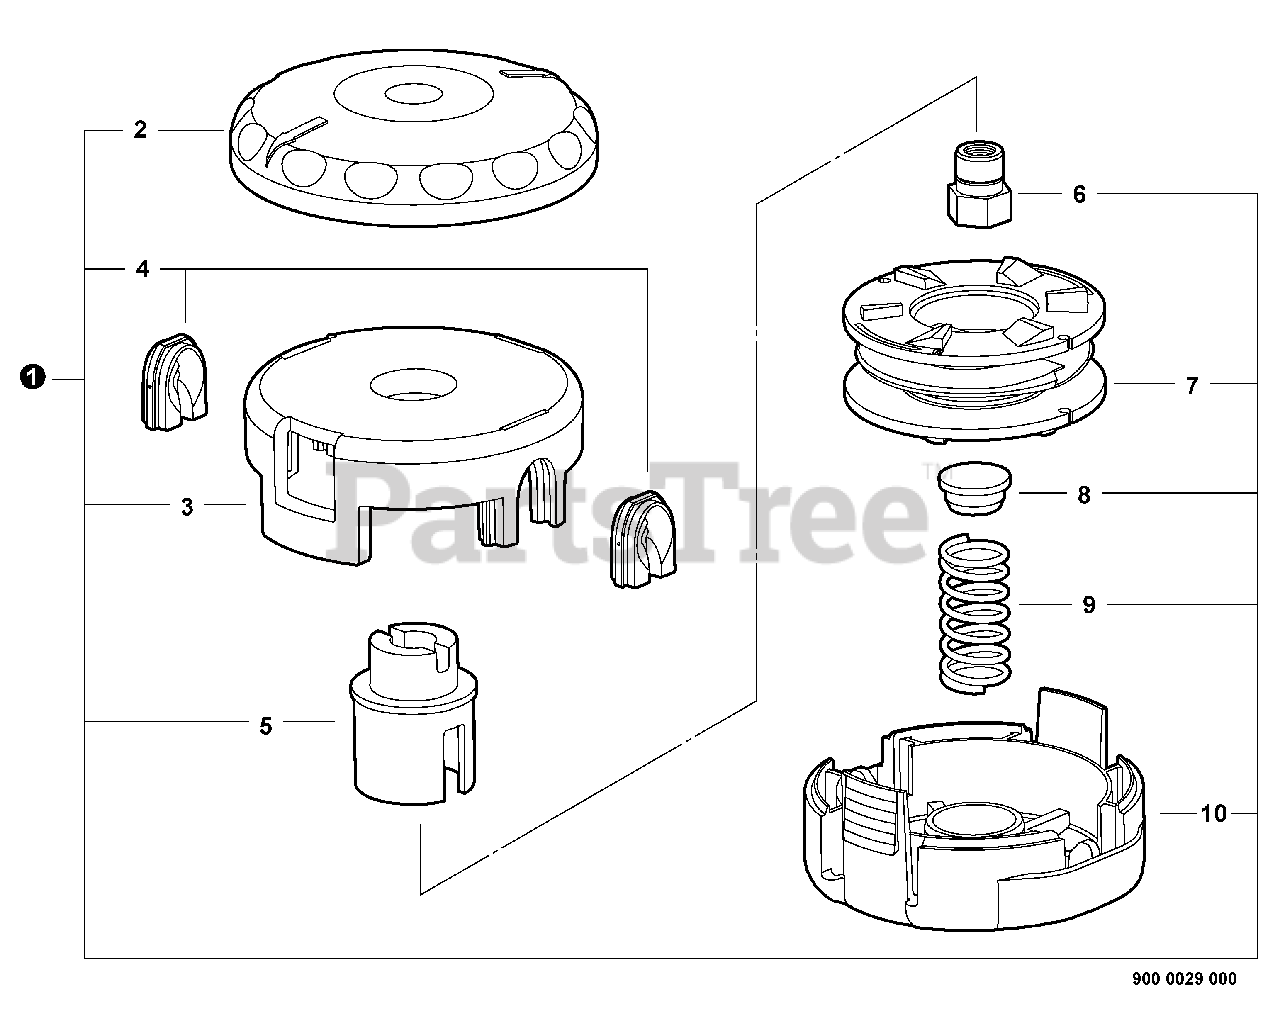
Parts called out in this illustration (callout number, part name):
1	TRIMMER HEAD, SPEED-FEED® 375
3	HOUSING, SPOOL
5	HUB, SPOOL
6	BUSHING LH M10×1.25 FEMALE
7	SPOOL LH
8	CAP, SPRING
9	SPRING, COMPRESSION
10	COVER, SPOOL
